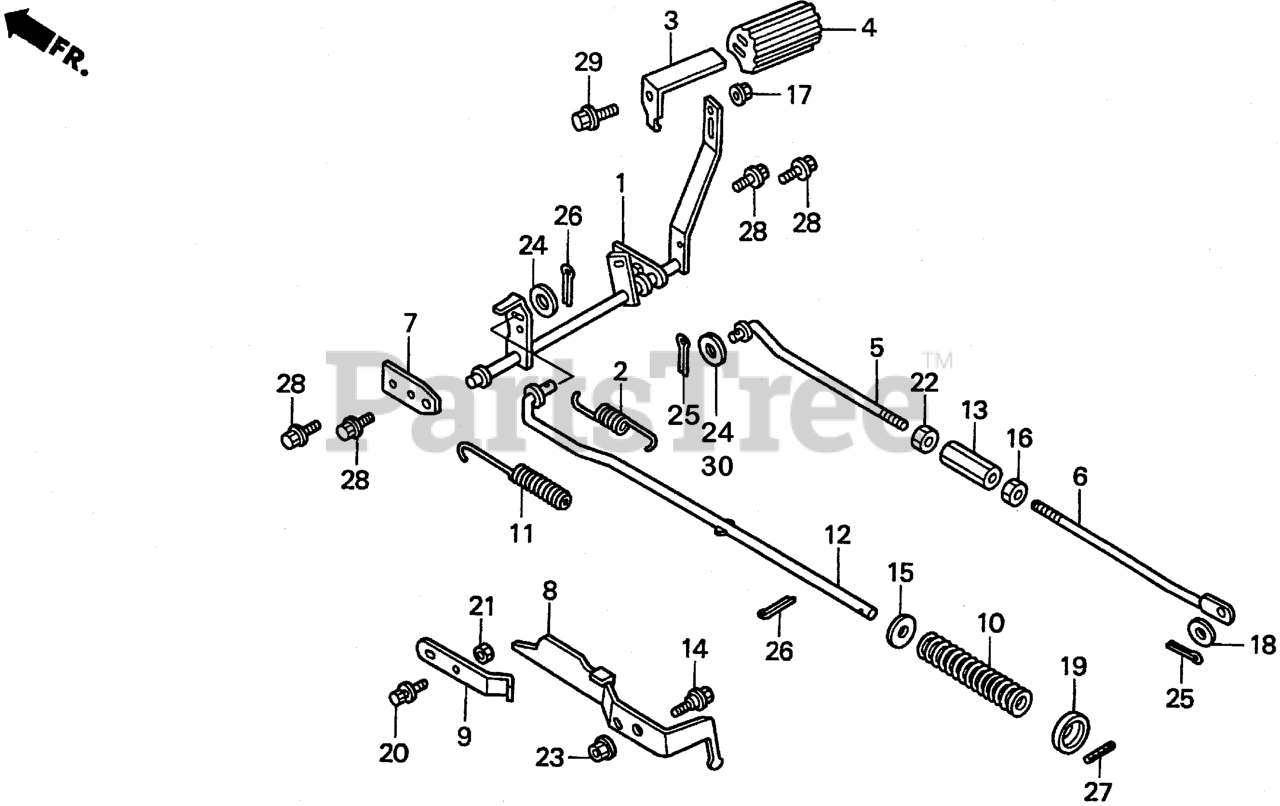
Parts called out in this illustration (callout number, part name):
1	PEDAL, BRAKE
2	SPRING, BRAKE PEDAL
3	BRACKET, BRAKE/CLUTCH
4	RUBBER, PEDAL
5	ROD A, RETURN
6	ROD B, RETURN
7	PIVOT, BRAKE PEDAL
8	LEVER, PARKING BRAKE
9	SPRING, PARKING BRAKE LEVER
10	SPRING, BRAKE LOAD SETTING
11	SPRING, BRAKE DAMPER
12	ROD, RR. BRAKE
13	JOINT (12MM)
14	BOLT, ADJUSTING ARM
15	WASHER, PLAIN (11MM)
16	NUT, L. HEX. (12MM)
17	NUT, FLANGE (8MM)
18	WASHER (13X20)
19	WASHER, PLAIN (0.63)
20	BOLT-WASHER (5X12)
21	NUT, HEX. (5MM)
22	NUT, HEX. (12MM)
23	NUT, FLANGE (8MM)
24	WASHER, PLAIN (10MM)
25	PIN, SPLIT (3.0X25)
25	PIN, COTTER (3.0X45)
26	PIN, SPLIT (4.0X22)
27	PIN, SPRING (4X25)
28	BOLT, FLANGE (8X18)
29	BOLT, FLANGE (8X28)
30	WASHER, PLAIN (12MM)
